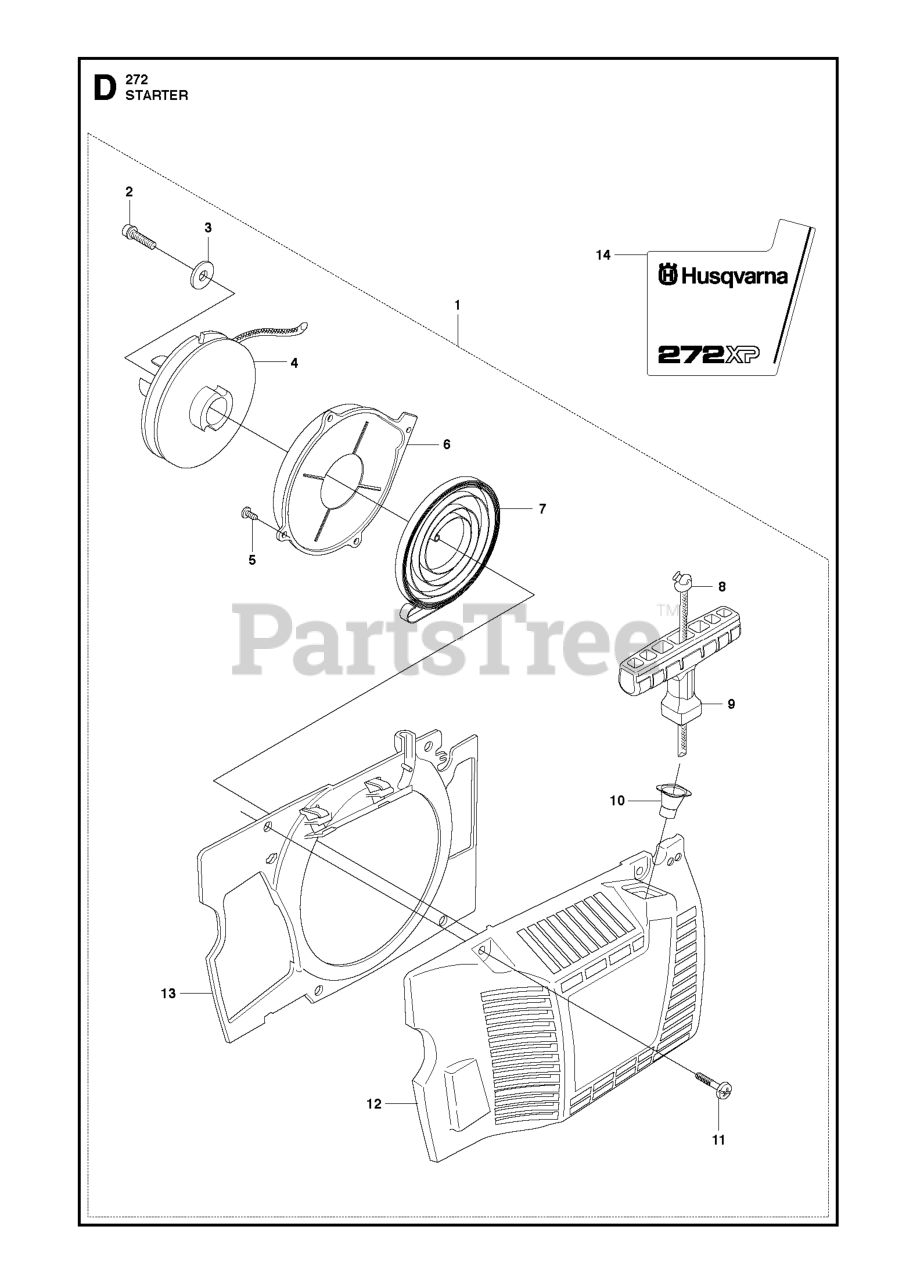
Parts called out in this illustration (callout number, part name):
1	WHEEL.STEER.HUSQ.SR.498.OVMLD
2	AXLE.SVC.ASM CAST IRON.TEX
4	SPINDLE.WELDED.LH.16"TEX
5	SPINDLE.WELDED.RH.16"TEX
6	THRUST WASHER
9	CAP.SPINDLE.BLACK
14	WASHER, LOCK 3/8
15	NUT CROWNLOCK 3/8-24
16	SHAFT.STEER.STEALTH.DD
19	PLATE.STEER.DDL.NLT/NG
21	ADAPTER, WHEEL STNG..
22	STEERING.SUPT.LOWER.
26	INSERT.CAP.WHL.STRG.HUSQ.PREM
28	SCREW, 3/8-16X3/4
35	GEAR.SECTOR.PLATE.DDL.
45	WASHER 9/16"ID, 2 3/8"OD
50	NUT LOCK FLG 3/8-16 UNC
51	NUT.HEX.1/2-20
53	WASHER.HARDENED
55	SPACER.BRACE.AXLE
58	BOLT.SHOULDER.SECTOR.P
59	WASHER.THURST.SECTOR.S
60	NUT FLANGE LOCK 5/8-11
61	DRAGLINK.LH.BALLSTUD.D
62	DRAGLINK.RH.BALLSTUD.D
63	SCREW
64	RETAINER.CLIP.SPRING.S
65	BRACE.AXLE.FRONT.NLT/N
66	BOLT HEX FGHD 7/16-14 X 3 SERR
67	BUSHING.PM.FRONT AXLE
68	NUT.LOCK.FLANGE.7/16
69	WASHER.1.5X.505X.118
70	BRKT.DECK.SUSPENSION.F
78	THRUST WASHER
118	BUSHING, AXLE CAST
122	CAP.GEAR.SECTOR.TEX
